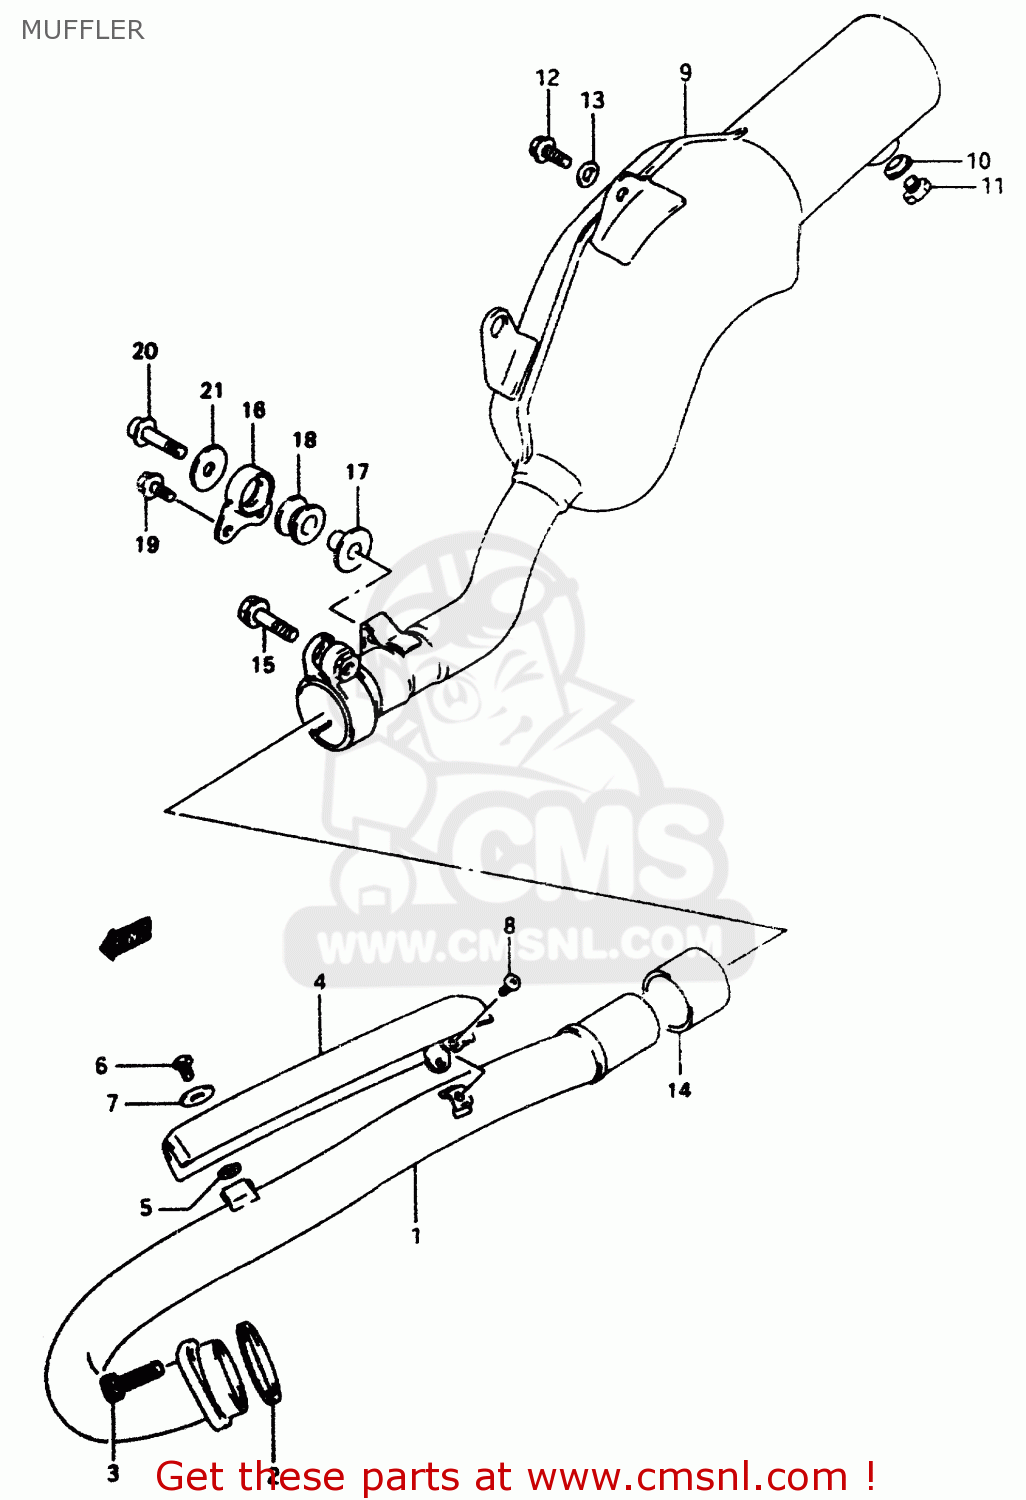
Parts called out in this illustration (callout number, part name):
1	PIPE,EXHAUST
2	GASKET,EXHAUST PIPE (NAS)
3	BOLT
4	COVER,EXHAUST PIPE
5	GASKET(5.8X13X1.4) (NAS)
6	SCREW(6X10)
7	WASHER(6.5X18X1)
8	SCREW
9	BODY,MUFFLER
10	GASKET(12.1X16.2X3.7) (NAS)
11	PLUG(12X9)
12	BOLT(8X20)
13	WASHER (8.5X19X2.3)
14	CONNECTOR,MUFFLER
15	BOLT
16	DAMPER,MUFFLER SUPPORT JOINT
17	SPACER(8.6X12X17.5)
18	CUSHION
19	BOLT 6X12
20	BOLT(8X30)
21	WASHER (8.5X20X1.6)
